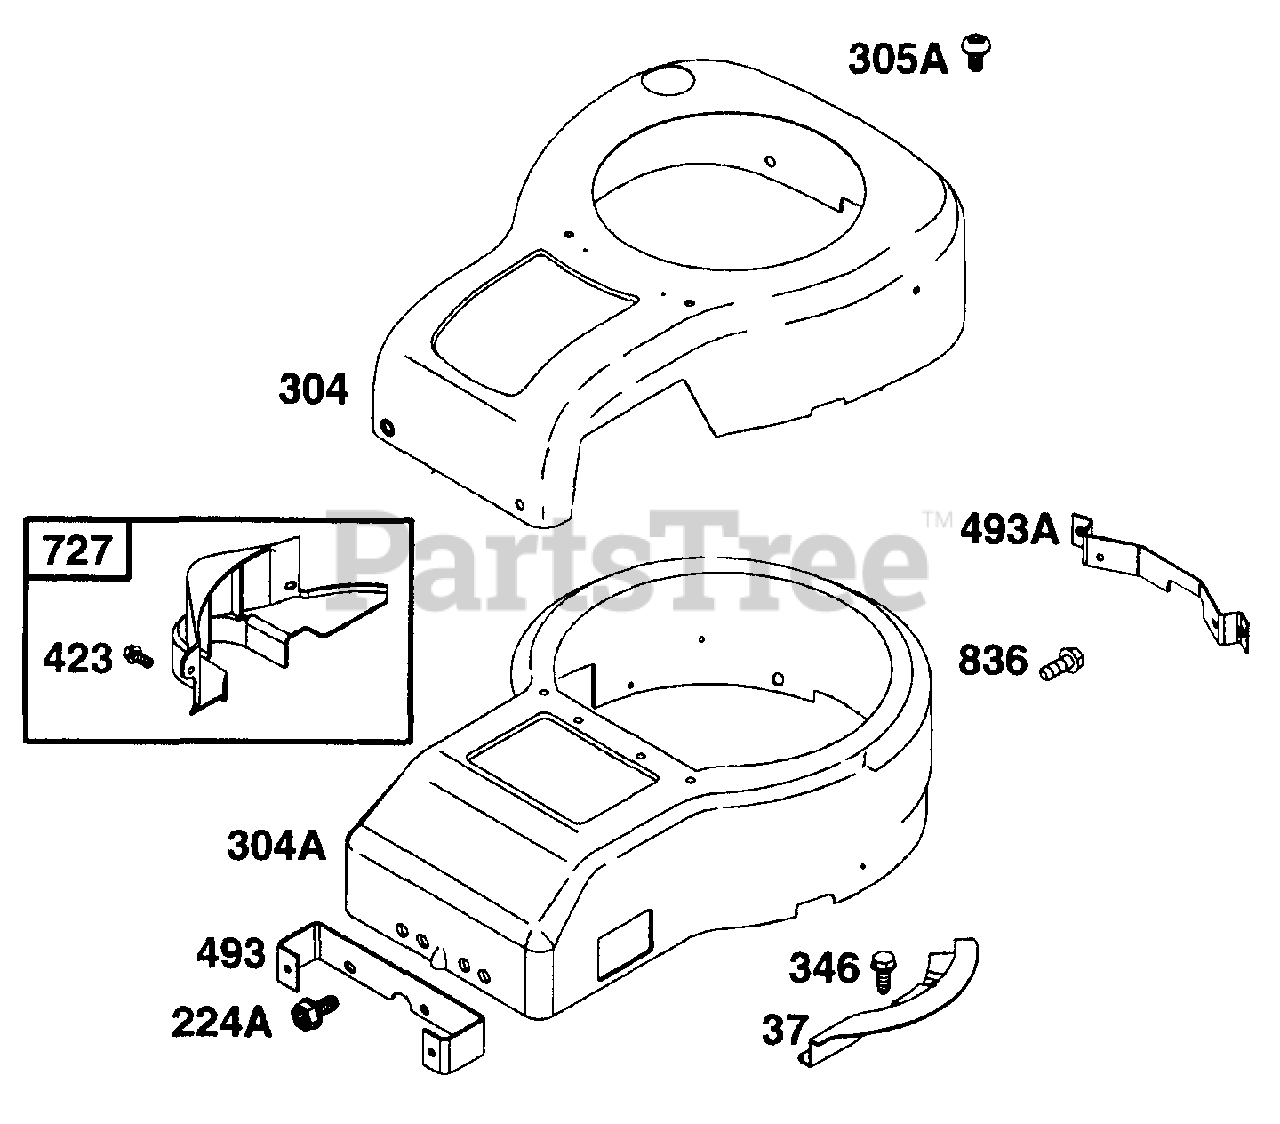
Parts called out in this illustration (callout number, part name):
37	Flywheel Guard
224A	Torx Hex Screw
304	Blower Housing Cover
304A	Blower Housing Cover
305A	Torx Screw
346	Hex Screw
423	Shoulder Screw
493	Mounting Bracket
493A	Mounting Bracket
727	Starter Drive Cover
836	Hex Screw
